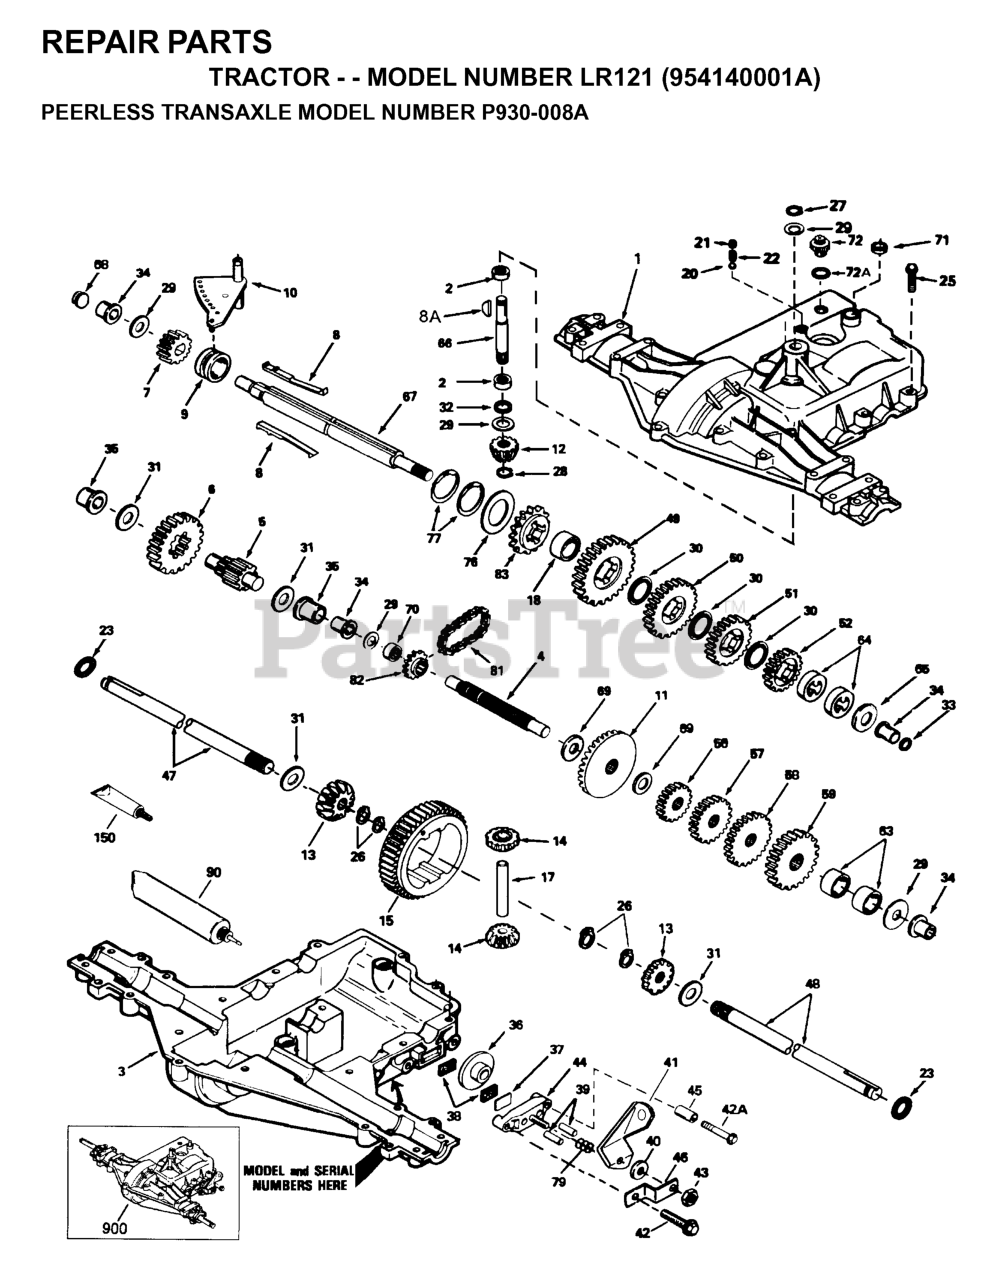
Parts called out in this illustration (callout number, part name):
2	Bearing, Needle
4	Shaft, Counter
8A	Woodruff Key No. 9
9	Collar, Shifter
11	Bevel Gear (42 teeth-steel)
15	Gear, Ring
18	Spacer, Neutral
20	Ball, Steel 5/16" diameter
21	Set Screw 3/18-16 x 3/8"
23	Ring, Seal
25	Screw, Flanged Hex Head, Thread Forming 1/4-20 x 1-1/4
26	Ring, Retainer (4 Required, Package of 2)
27	Retaining Ring
28	Ring, Retaining
29	Washer, Thrust
30	Washer, Thrust
31	Washer (.056 wide)
33	Seal, Square Cut
36	Disk, Brake
37	Plate, Brake pad
38	Brake Pad (pkg of 2)
39	Pin, Dowel
40	Washer, Flat
41	Lever, Brake
42A	Screw, 1 /4-20 x 2-1 /4"
43	Lock Nut 5/16-24
44	Holder, Brake pad
46	Bracket, Brake lever
47	Axle (11-15/16" long)
48	Axle (16-1/2" long)
52	Gear, Spur, 19 Teeth, Steel (4 th)
56	Gear, Spur, 12 Teeth (1 st)
63	Countershaft Spacer (1-1/8" x 3/8")
64	Brake Shaft Spacer (1-3/8" x 3/8")
66	Input Shaft (3.687" long)
69	Thrust Washer (.762 ID)
71	Seal, Square Cut
76	Washer, Thrust
77	Ring, Retaining, Inverted (Package of 2)
79	Piston Assembly
81	Chain, Roller (Number 41 Chain, 24 Links)
150	Gasket Eliminator (Loctite No. 515)
